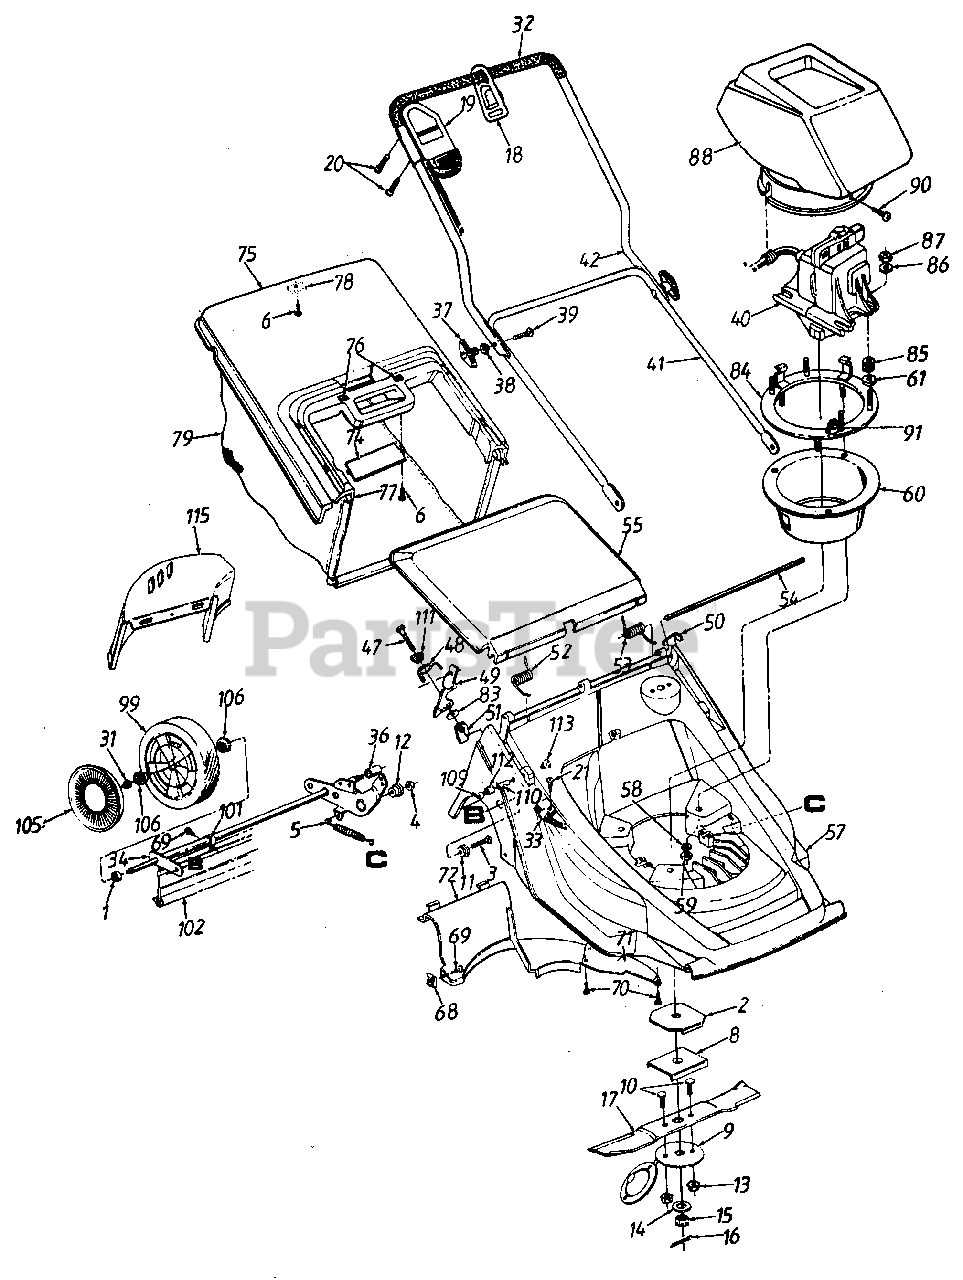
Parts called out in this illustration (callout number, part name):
1	Spacer .508" I.D. x .875" O.D.
2	Blade Adapter
3	Hex Wash. Hd. TT-Tap Scr. 3/8-16 x .75" Lg.
4	Hex L-Nut 3/8-24 Thd.
5	Extension Spring 6.12" Lg.
6	Truss Mach. Hi-Riser Tap Scr. #12 x .75" Lg.
8	Blade Adapter Insulator
9	Blade Insulator
10	Carriage Bolt 5/16-18 x .75" Lg.
11	Pivot Spacer-R.H.
12	Pivot Spacer-L.H.
13	Hex Keps Nut 5/16-18 Thd.
14	Fl-Wash. .516" I.D. x 1.5" Lg.
15	Slotted Hex Nut 1/2-20 Thd.
16	Cotter Pin 1" Lg.
17	18" Blade
18	Cord Restraint
19	Cord and Switch Ass'y. (Complete)
20	Self-Tap Scr. #7 x 1" Lg.
21	Pan Hd. Scr. #10-16 x .75" Lg.
31	Hex L-Nut 1/2-20 Thd.
32	Foam Grip
33	Clamp
34	Rear Axle Ass'y.
36	Spacer .55" I.D. x .755" O.D.
37	Knob Ass'y.
38	Saddle Washer .32" I.D.
39	Curved Carr. Bolt 5/16-18 x 2" Lg.
40	Motor & Switch Ass'y.
41	Lower Handle
42	Upper Handle
47	Hex Bolt 5/16-18 x 1.25" Lg.
48	Handle Latch Spring-R.H.
49	Handle Lock-R.H.
50	Handle Lock-L.H.
51	U-Nut 5/16-18 Thd.
52	Torsion Spring-R.H.
53	Torsion Spring-L.H.
54	Hinge Pin 14.5" Lg.
55	Chute Door
57	Deck Ass'y.
58	Fl-Wash. 5/16" I.D. x .75" O.D.
59	Hex L-Nut 5/16-18 Thd.
60	Motor Shield
61	Insulator Spacer
68	U-Nut #10-16 Thd.
69	Truss Mach. B-Tap Scr. #10 x .5" Lg.
70	Truss Mach. Hi-Riser Tap Scr. #12x 1" Lg.
74	Hardtop Cover Plate
75	Hardtop Cover
76	Magnetic Catch
77	Catcher Frame
83	Bell-Wash. 5/16" I.D. x .88"
84	Plate Ass'y.
85	Insulator-Motor Housing
86	Fl-Wash. .26" I.D. x .72" O.D.
87	Hex Top L-Nut 1/4-20 Thd.
88	Motor Cover
90	Truss Mach. Scr. #10-24 x .75" Lg.
99	Wheel Ass'y. Comp.
101	Clamp
102	Rear Flap
105	Hub Cap
106	Ball Brg. 1/2" I.D.
109	Truss Hd. Scr. 1/4-20 x 2" Lg.
110	Spacer .26" I.D. x 1.20" Lg.-R.H.
111	Latch Plate Bushing
112	Spacer .383" I.D. x .562" Lg.
113	Propel Nut 1/4-20 Thd.
115	Rear Discharge Chute Deflector
